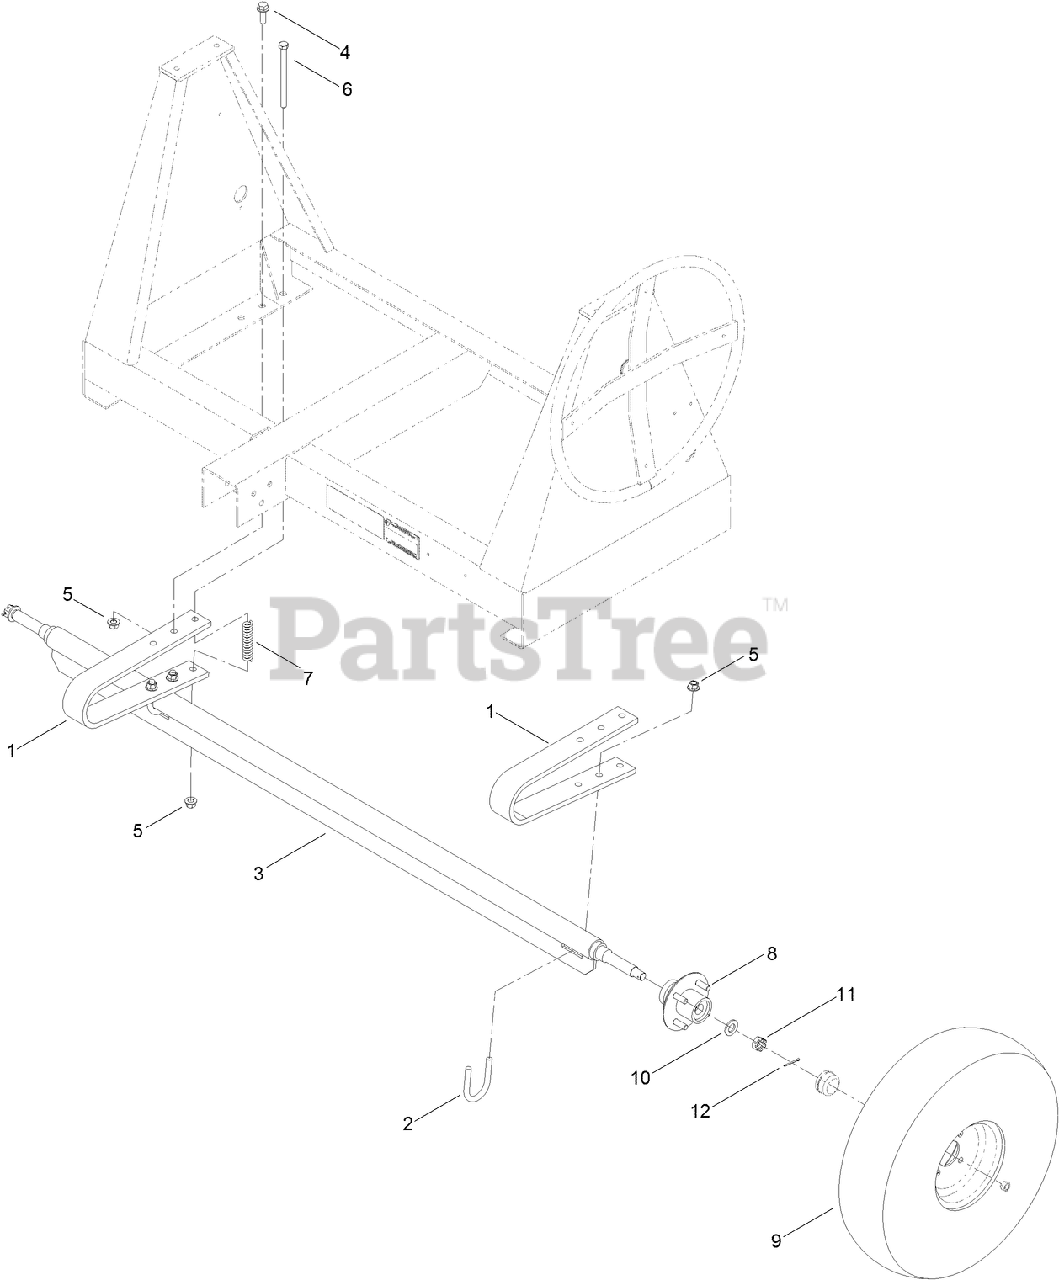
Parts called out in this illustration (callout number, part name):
1	SPRING-LEAF
2	BOLT-U
3	AXLE-SPRING
4	SCREW-HHF
5	NUT-LOCK
6	SCREW-HH
7	SPRING-COIL
8	HUB ASM
9	TIRE AND RIM ASM
10	WASHER-FLAT
12	PIN-COTTER
